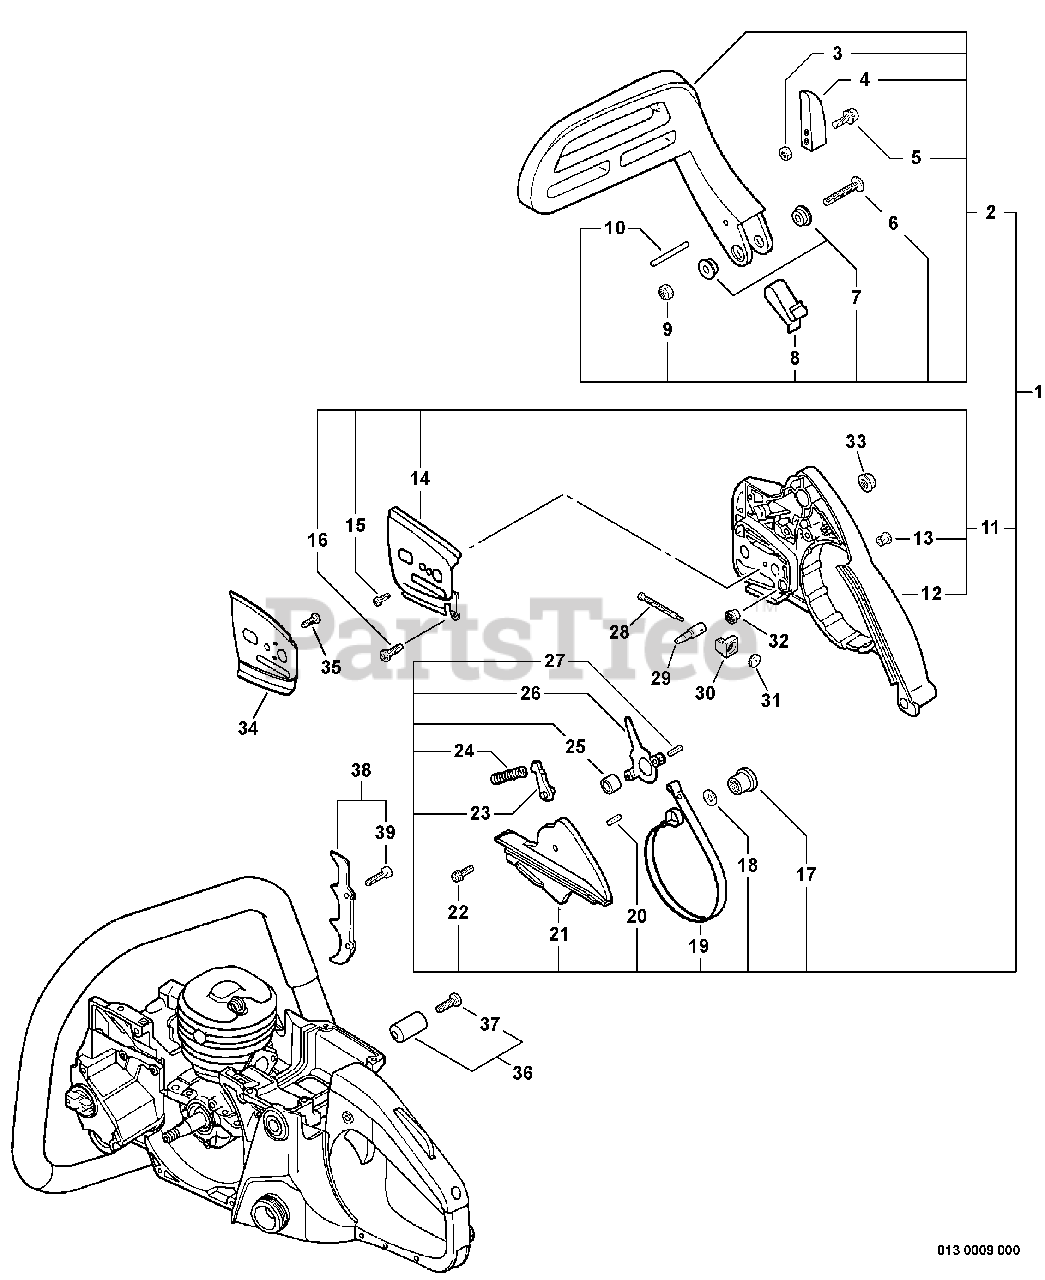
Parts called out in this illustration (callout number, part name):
1	CHAIN BRAKE ASSY
2	BRAKE LEVER ASSY
4	WEIGHT, BRAKE
5	SCREW 4×18
6	SCREW 5×32
7	COLLAR 5.3×10×13×L5
8	SPRING, FLAT
9	NUT, LOCK M5
10	PIN 3×24
11	SPROCKET GUARD ASSY
12	GUARD, SPROCKET
13	PLUG
14	PLATE, GUIDE - OUTER
15	SCREW 3×6
16	SCREW 4×10
17	ADJUSTER, BRAKE
18	WASHER 8
19	BAND, BRAKE
20	PIN, SPRING 2.5×12
21	COVER, BRAKE
22	SCREW 4×10
23	STOPPER, BRAKE
24	SPRING, COMPRESSION
25	WASHER 5.2×12×14
26	LEVER, BRAKE
27	PIN, SPRING 4×8.8
28	SCREW, CHAIN TENSION
29	TENSIONER, CHAIN
30	COLLAR 8
31	GEAR, BEVEL
32	GEAR, BEVEL
33	NUT, FLANGE M8×1.25
34	PLATE, GUIDE - INNER
35	SCREW 4×6
36	CHAIN CATCHER KIT
37	SCREW 5×18
38	SPIKE KIT, BUMPER
39	BOLT 5×12
